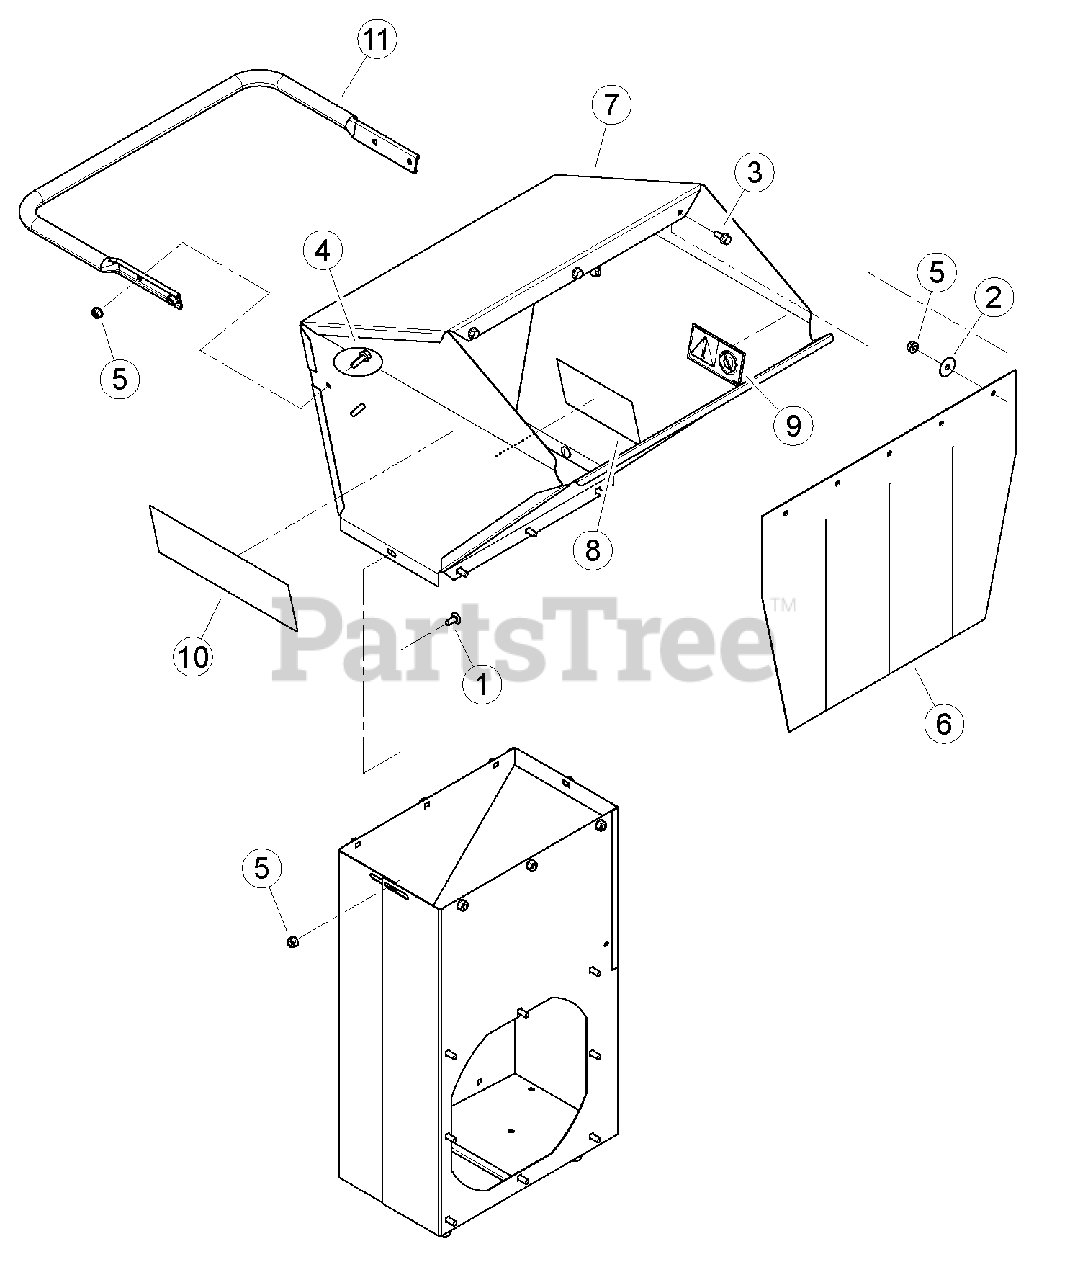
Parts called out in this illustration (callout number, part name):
1	BOLT, 5/16-18 X 3/4 SN GR5 CRG
2	WASHER, 5/16" FENDER ZP
3	BOLT, 5/16 X 3/4 FLANGE NC
4	BOLT, 5/16 X 1 FLANGE NC
5	NUT, 5/16-18 NYLOCK FLANGE
6	BELTING, EURO HOPPER
7	ASSEMBLY, WIDE "CE" HOPPER W/ DECALS
8	DECAL, BLADE DANGER ISO
9	DECAL, SHREDDER SIZE ISO
10	DECAL, ECHO BEARCAT 12.00 X 4.00
11	HANDLE, EURO HOPPER
